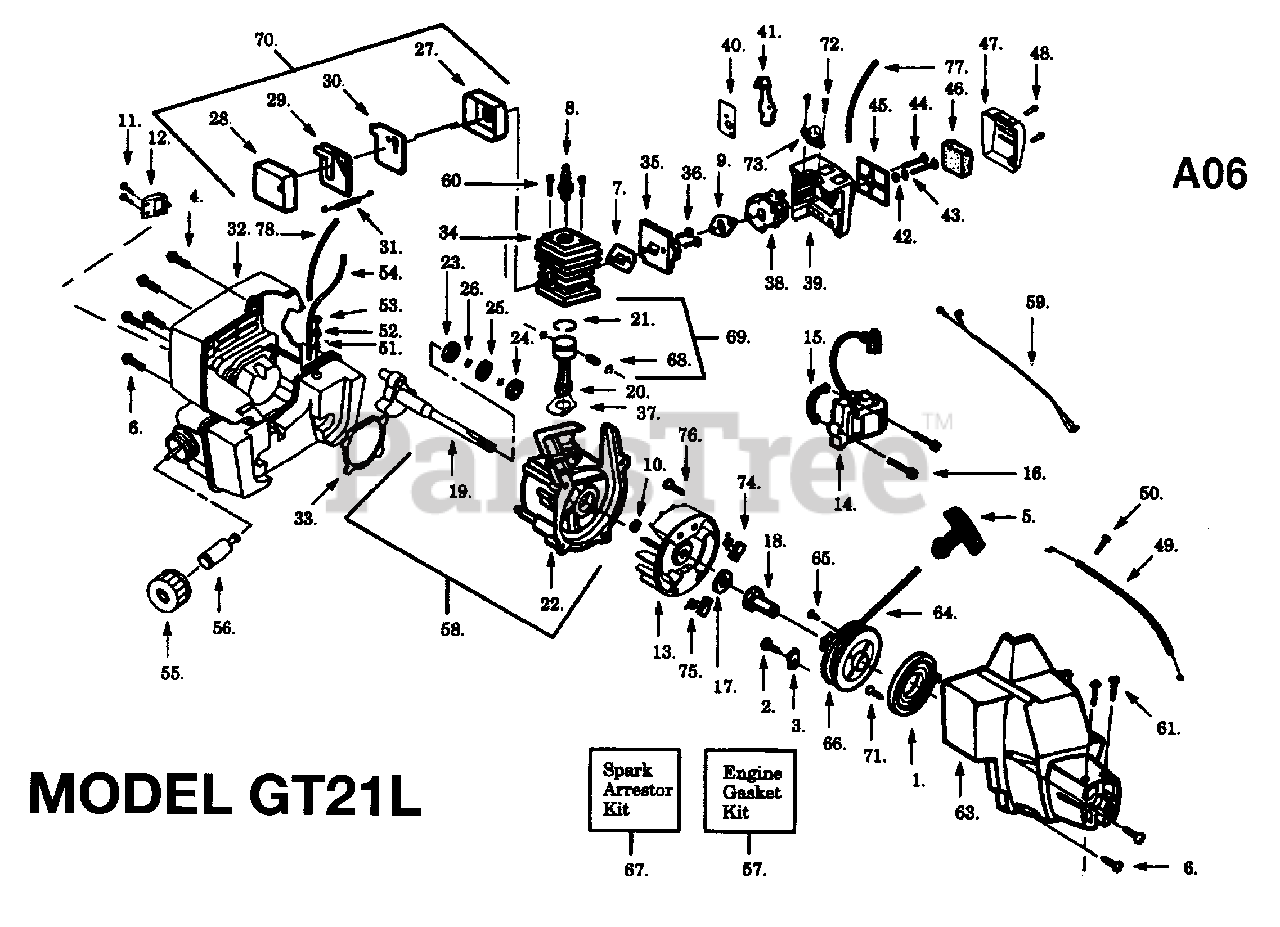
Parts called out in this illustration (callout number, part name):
1	SPRING-STARTER
2	SCREW 8-16 X 9/16 (PLAS
5	HANDLE-STARTER
6	SCREW - SHROUD
8	SPARK PLUG (RCJ-8Y) NLA
9	GASKET - CARBURETOR
11	SCREW-8-18 X 5/18(RECES
12	MUFFLER GUARD
13	FLYWHEEL
14	IGNITION MODULE
15	SPACER - IGNITION MODULE
17	WASHER FLAT
18	COUPLING-DRIVE
19	CRANKSHAFT ASSEMBLY
20	CONNECTING ROD ASSEMBLY
21	PISTON RING
22	CRANKCASE ASSY
23	BEARING
25	SEALING RING
26	RETAINING RING
27	MUFFLER BODY
28	MUFFLER COVER
29	MUFFLER BAFFLE - EXIT
30	MUFFLER BAFFLE - FIRST
31	MUFFLER SPRING
33	GASKET, CRANKCASE
34	CYLINDER
35	CARB ADAPTOR KIT
36	SCREW - CARB. ADAPTOR
37	GASKET - CYLINDER
38	CARBURETOR
40	CHOKE PLATE
41	CHOKE SHUTTER
43	CHOKE SPACER
45	FILTER PLATE
46	AIR FILTER FOAM
47	AIR FILTER COVER
48	SCREW - THROTTLE HOUSING
49	THROTTLE CABLE
51	VALVE-CHECK (DUCKBILL)
55	CAP ASSY W/ RETAINER
56	FUEL PICK UP ASSY
58	CRANKCASE/CRANKSHAFT ASSEMBLY
59	LEAD WIRE ASSEMBLY
61	SCREW - PINCH CLAMP
62	LOCKNUT-HEX 10-24
66	STARTER PULLEY KIT
67	KIT-SPARK ARRESTOR (OLD STYLE)
68	WRIST PIN RET.
69	PISTON KIT
70	MUFFLER KIT
72	SCREW - PRIMER ASSEMBLY
73	AIR PURGE BUBBLE
78	FUEL LINE - PRIM/TNK
